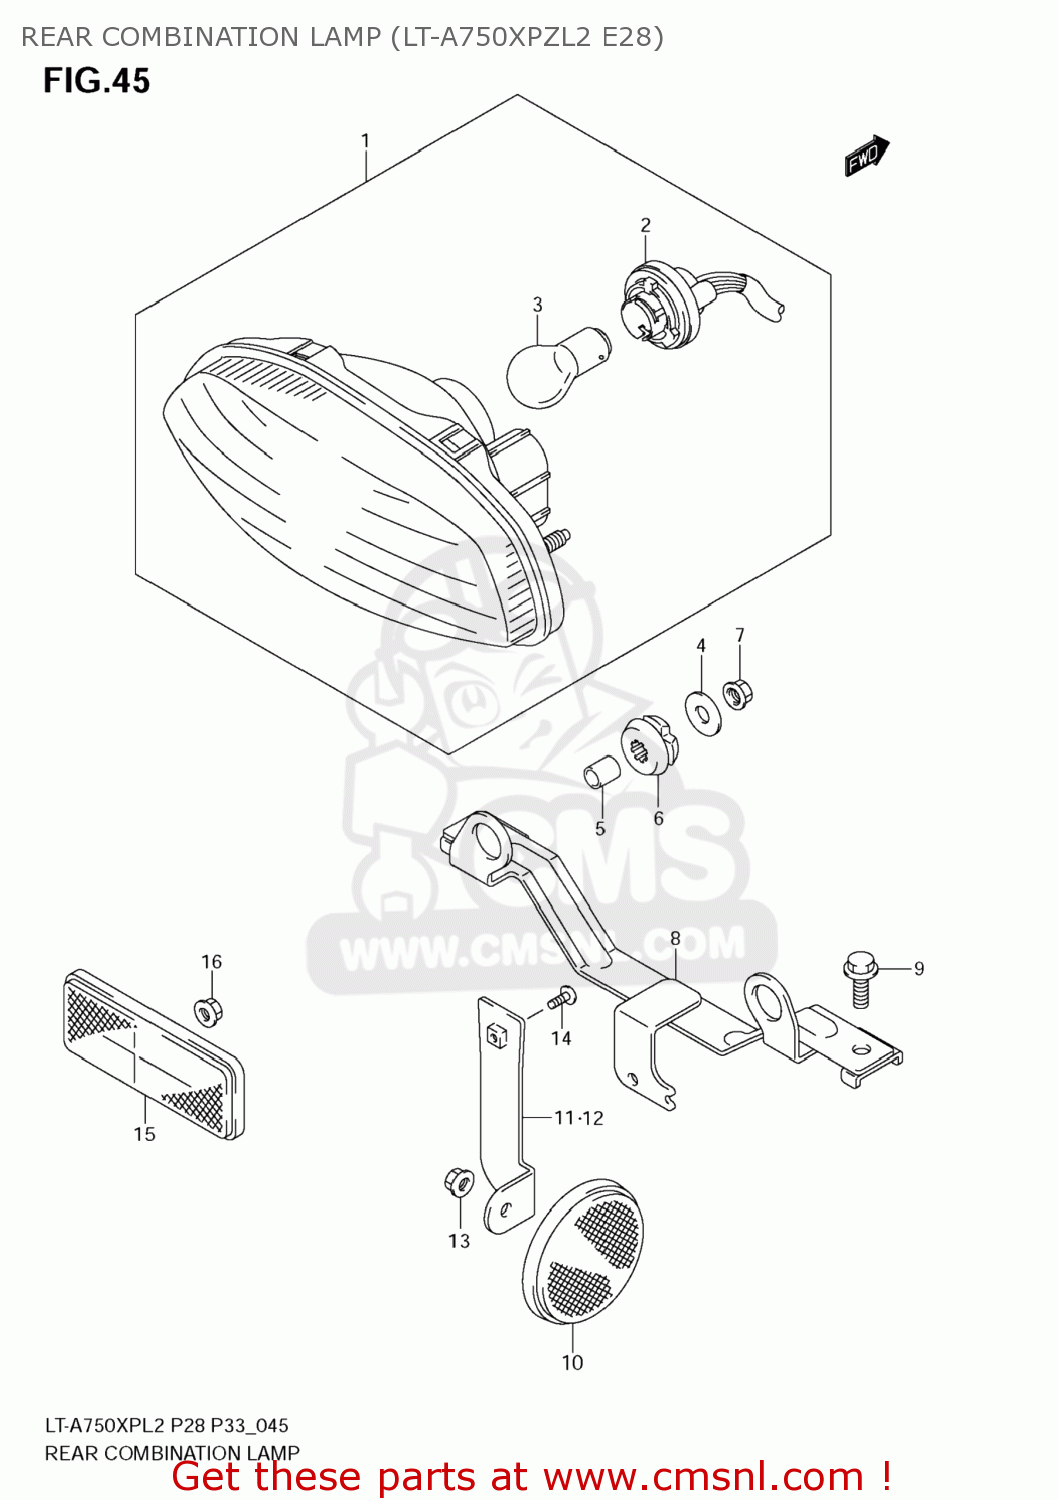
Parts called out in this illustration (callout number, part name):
1	LAMP ASSY,RR COMBINATION
2	BULB(12V21/5W,BF141-49642A)
3	SOCKET & BULB
4	WASHER(6.5X20X1.2)
5	SPACER(6.5X9X10.5)
6	CUSHION
7	NUT
8	BRACKET,RR COMBINATION LAMP
9	BOLT
10	REFLECTOR ASSY,RR SIDE
11	BRACKET,RR SIDE RR,R
12	BRACKET,RR SIDE RR,L
13	NUT
14	SCREW(5X8)
15	REFLECTOR ASSY,RR
16	NUT
